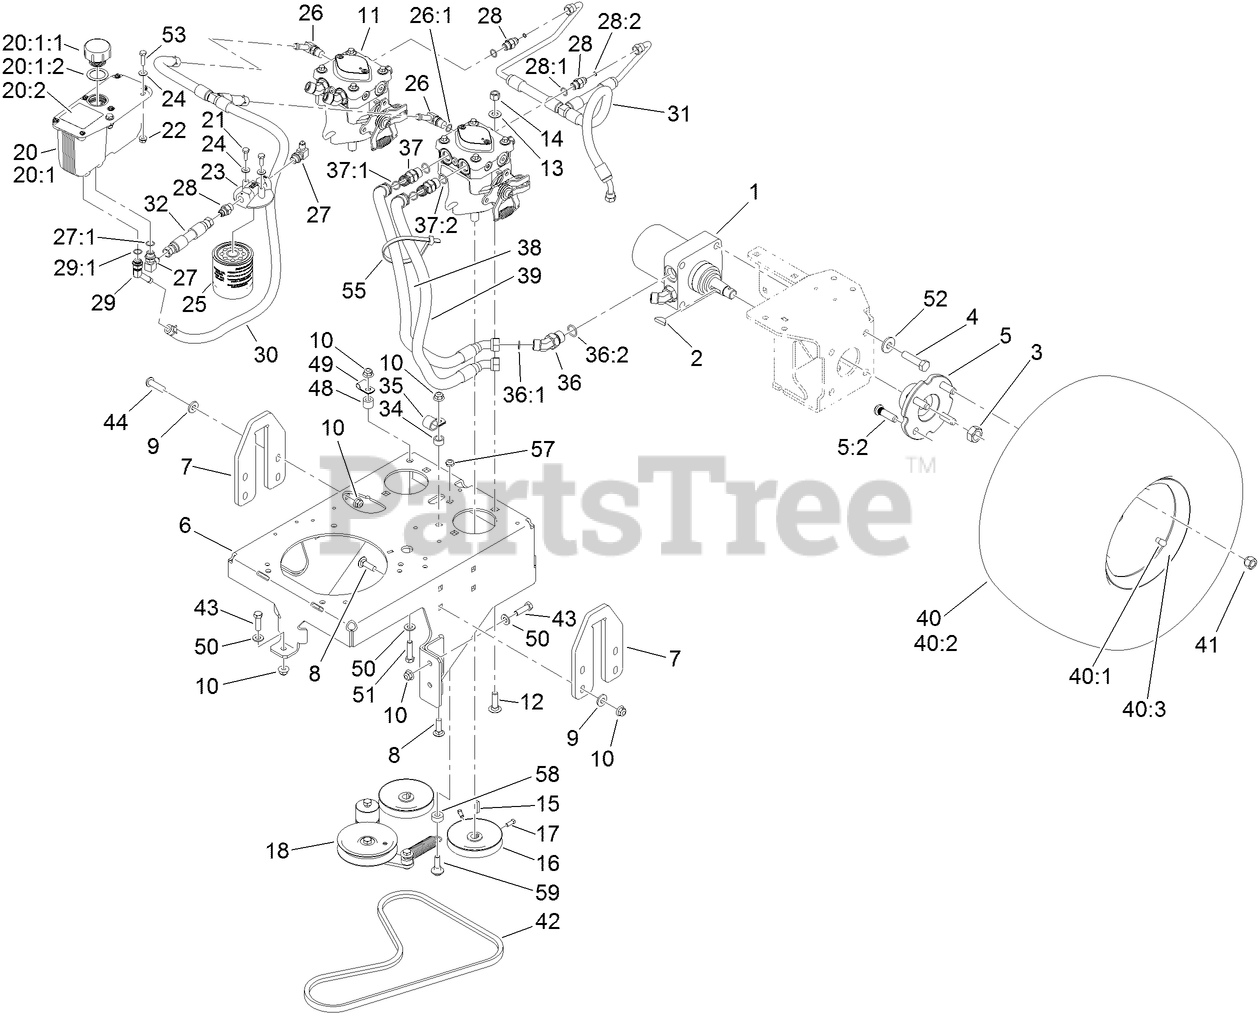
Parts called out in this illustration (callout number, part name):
1	HYD MOTOR ASM
2	KEY-WOODRUFF
3	NUT-MOTOR, WHEEL
4	SCREW-HH
5	WHEEL HUB ASM
5:2	STUD-TYPE, DRIVE
6	BASE-ENGINE
7	PLATE-LIFT
8	BOLT-CARR
9	WASHER-BELLEVILLE
10	NUT-HF, NI
11	HYDRAULIC PUMP ASM
12	BOLT-CARR
13	WASHER-FLAT
14	NUT-LOCK, NI
16	PULLEY-PUMP
17	SCREW-SET
18	PUMP IDLER ASM
20	HYD RESERVOIR ASM
20:1	Reservoir-HYD
20:1:1	CAP-RESERVOIR, HYD
20:1:2	GASKET-CAP
20:2	DECAL-WARNING
21	SCREW-HH
22	NUT-HHF
23	HEAD-FILTER
24	WASHER-FLAT
25	ELEMENT-FILTER, 25 MICRON
26	FITTING-ELBOW, 90
26:1	O-RING
27	FITTING-ELBOW, 90 DEG
27:1	O-Ring
28	FITTING-STRAIGHT
28:1	O-Ring
28:2	O-RING
29	FITTING-BARBED, 45 DEG
29:1	O-RING
30	TANK HOSE ASM
31	CHARGE HOSE ASM
32	HYD HOSE ASM
34	SPACER-WHEEL
35	CLIP-LOOM
36	FITTING-HYD, 45 DEG
36:1	O-RING
36:2	O-RING
37	FITTING-HYD, 45 DEG
37:1	O-RING
37:2	O-RING
38	HYD HOSE ASM
39	HYD HOSE ASM
40	WHEEL ASM
40:1	STEM-VALVE
40:3	RIM-8 INCH
41	NUT-LUG
42	BELT-V, LOWER PTO
43	SCREW-HH
44	SCREW-HSBH
48	SPACER-PIVOT
49	CLIP-TUBE
50	WASHER-FLAT
51	SCREW-HH
52	WASHER-SPRING
53	SCREW-HH
55	TIE-CABLE
57	NUT-LOCK, NI
58	SPACER
59	SCREW-SHOULDER, HWH
